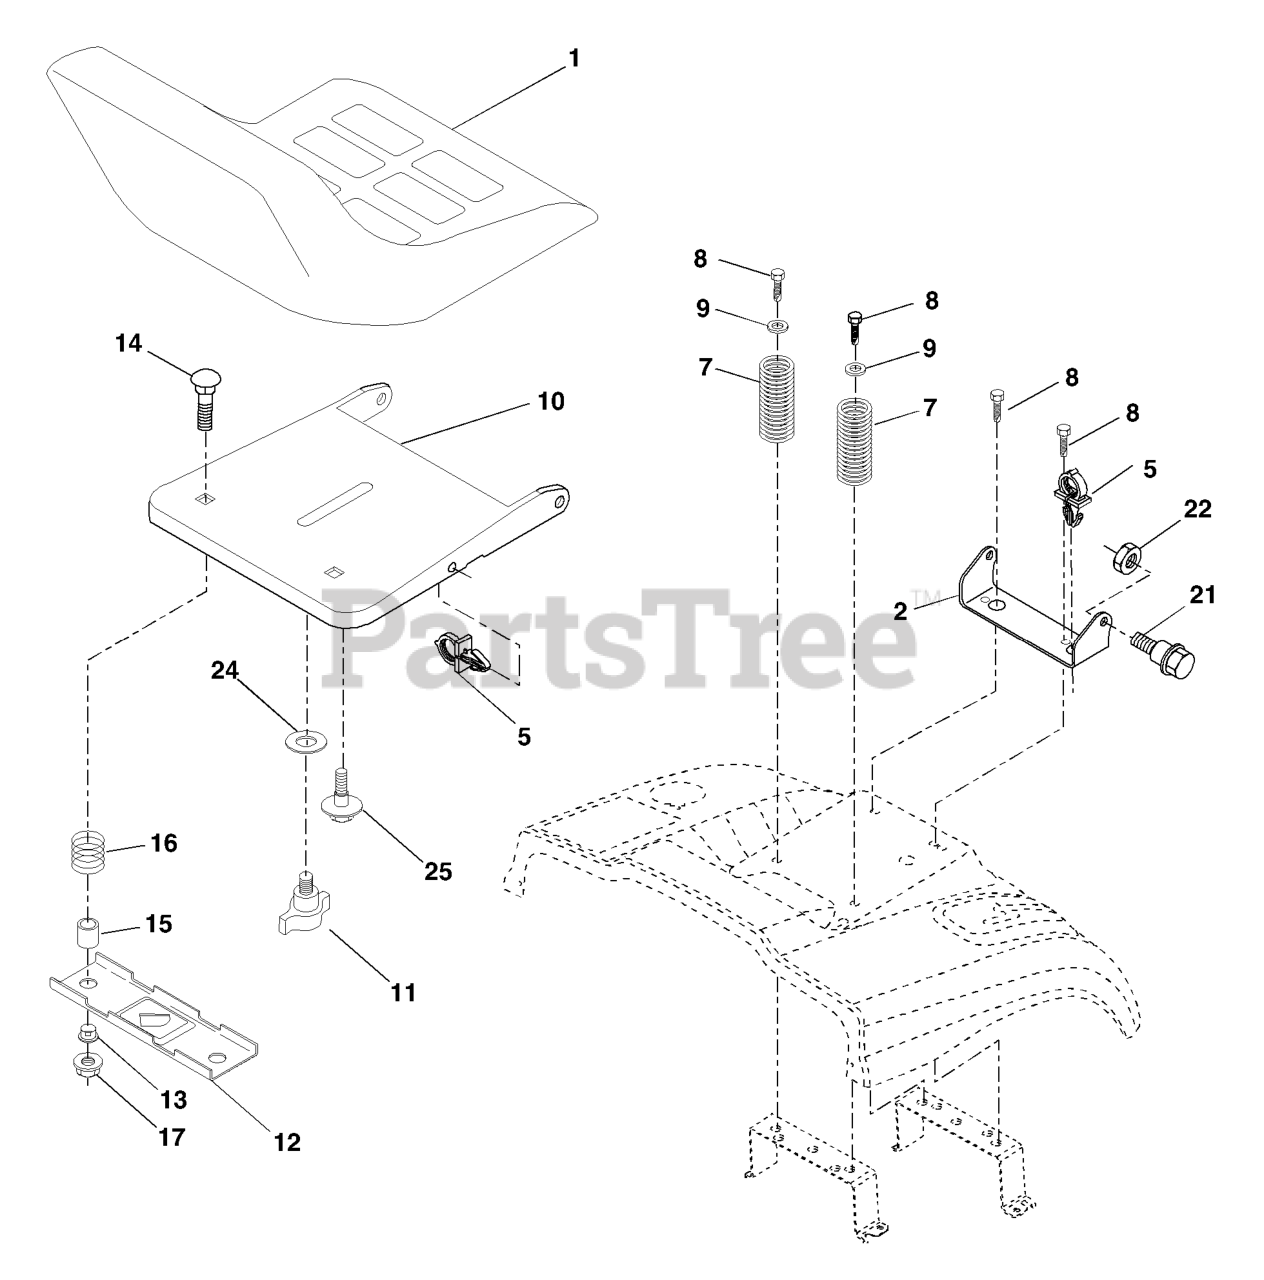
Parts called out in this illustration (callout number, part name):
1	SEAT, GRAY
2	SEAT PIVOT BRKT
7	SPRING COMPRESSION
8	SCREW THDROL 3/8-16 X 1-1/2
9	WASHER
10	PAN, SEAT
11	KNOB.SEAT.ADJ.WINGNUT
12	BRKT SWITCH
14	BOLT.ROUND.HEAD.SQUARE.NECK
15	SPACER SPLIT 28X.96
17	NUT T
21	BOLT SHOULDER 5/16-18
22	NUT.71038.31-18.HEX.NYLOCK
24	WASHER GT
25	BOLT,SHOULD
